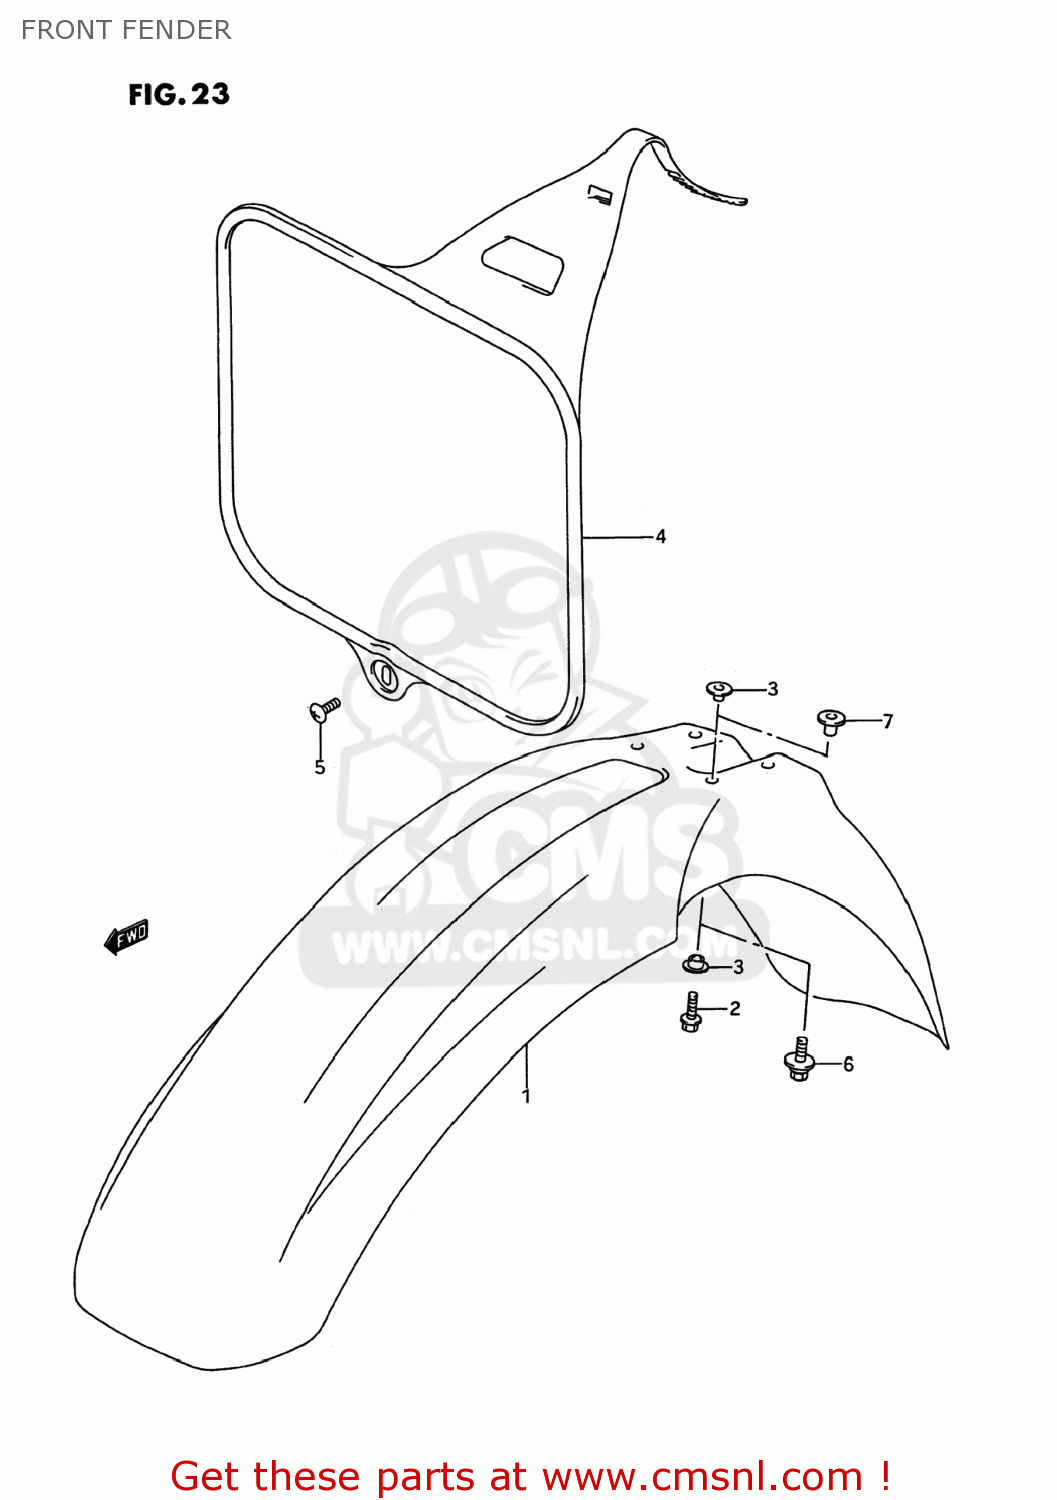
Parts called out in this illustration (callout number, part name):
1	FENDER,FRONT
2	BOLT
3	WASHER
4	PLATE,NUMBER FRONT(WHITE)
5	SCREW
6	BOLT(6X16)
7	WASHER
